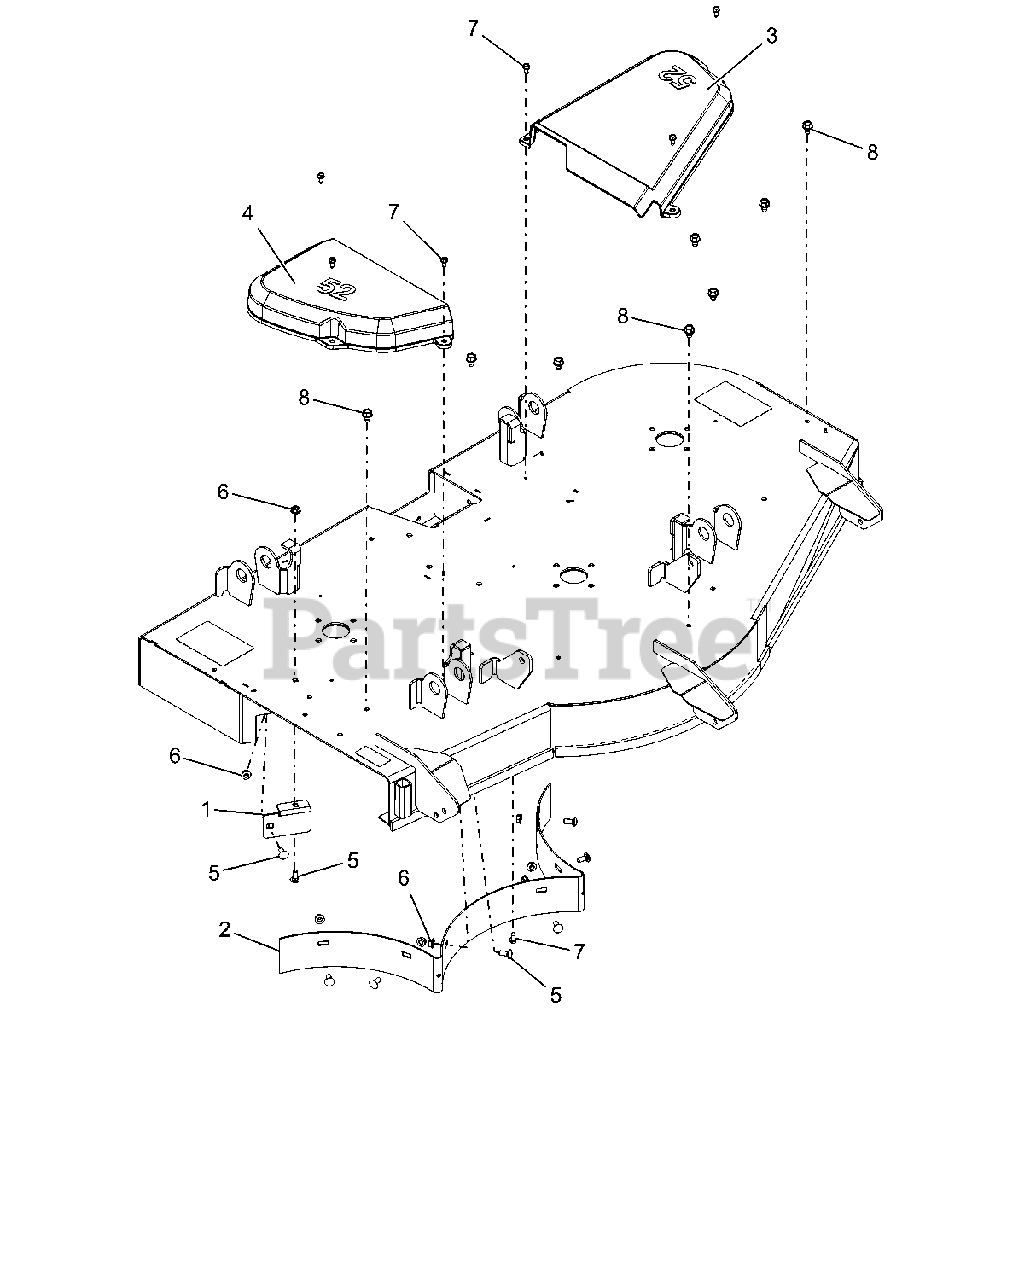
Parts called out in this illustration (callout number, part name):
1	STRIP, DEFLECTOR - 52"
2	BAFFLE, REAR - REMOVABLE 52"
3	COVER, BELT 52" LH
4	COVER, BELT 52" RIGHT
5	@BLT-RDHDSQNK .31-18X.75 G5YZ
6	@NUT-LK-TOP-FLG .31-18 YWZC
7	SCR-TAP .25-20X.50 HWH TR YWZ
8	@SCR-TAP .38-16X.50 HWH TR YWZ
